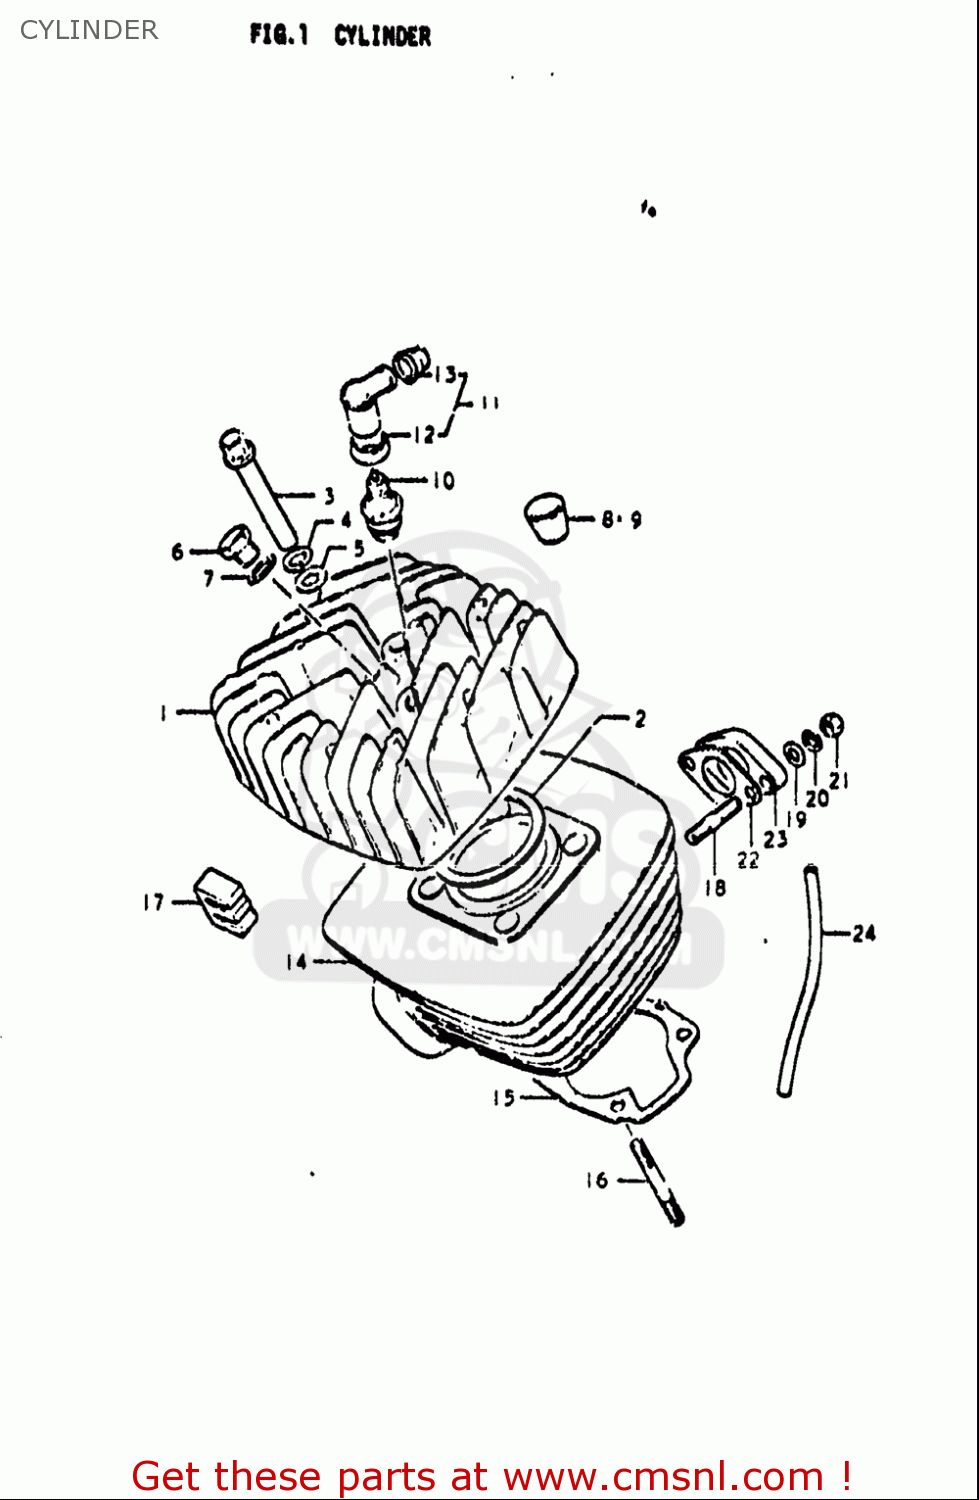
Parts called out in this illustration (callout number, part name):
2	GASKET,CYLINDER HEAD (NAS)
3	NUT
4	WASHER,LOCK
5	WASHER
6	PLUG
7	GASKET(14X19.2X2) (NAS)
8	PAD,CYLINDER
10	SPARK PLUG W22FS
11	CAP,SPARK PLUG
12	SEAL,SPARK PLUG
13	SEAL,HIGH TENSION CORD
15	GASKET,CYLINDER (MCA)
16	STUD BOLT
17	PAD,CYLINDER
18	BOLT,STUD
19	WASHER
20	WASHER,LOCK
21	NUT
22	GASKET,CARBURETOR (NAS)
23	GASKET,CARBURETOR INSULATOR (NAS)
24	HOSE(3X5X600)
